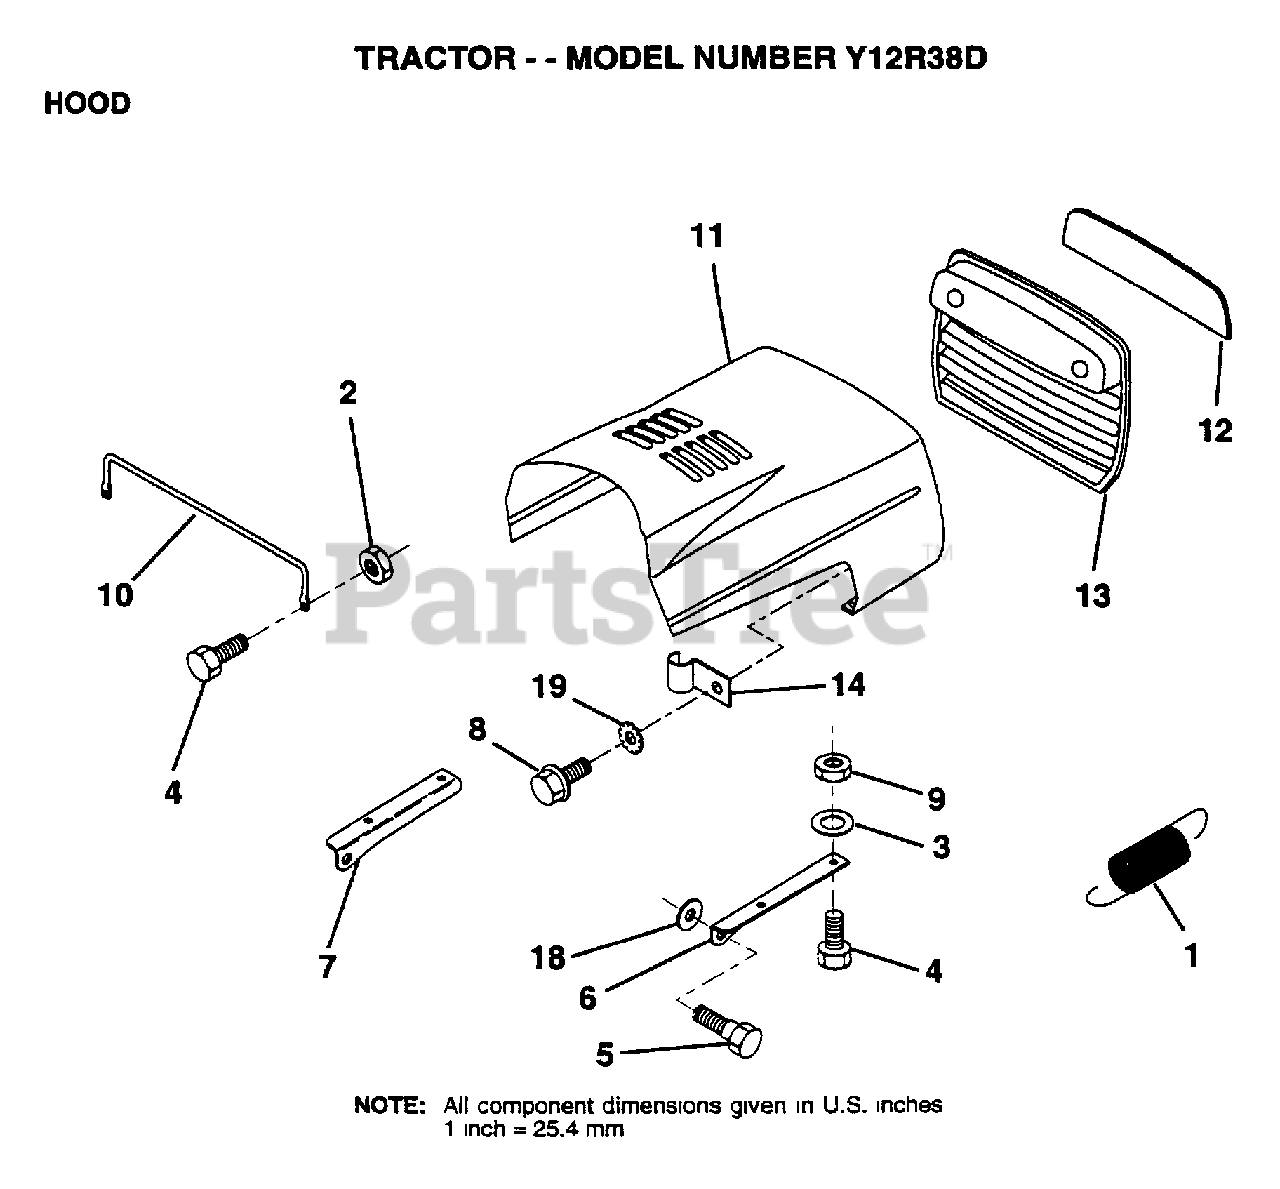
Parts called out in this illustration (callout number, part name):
1	EXT SPRING
2	NUT HXKEP 1/4X20
3	WASHER
5	BOLT.SHLD.5/16-18
6	BRKT HOOD RH
7	BRKT HOOD LH
8	SCREW SLTD HXHD
9	NUT
10	"BRACE,HOOD"
11	HOOD
12	LENS
13	GRILL
14	CLIP T
18	WASHER
19	LOCKWASHER GT
